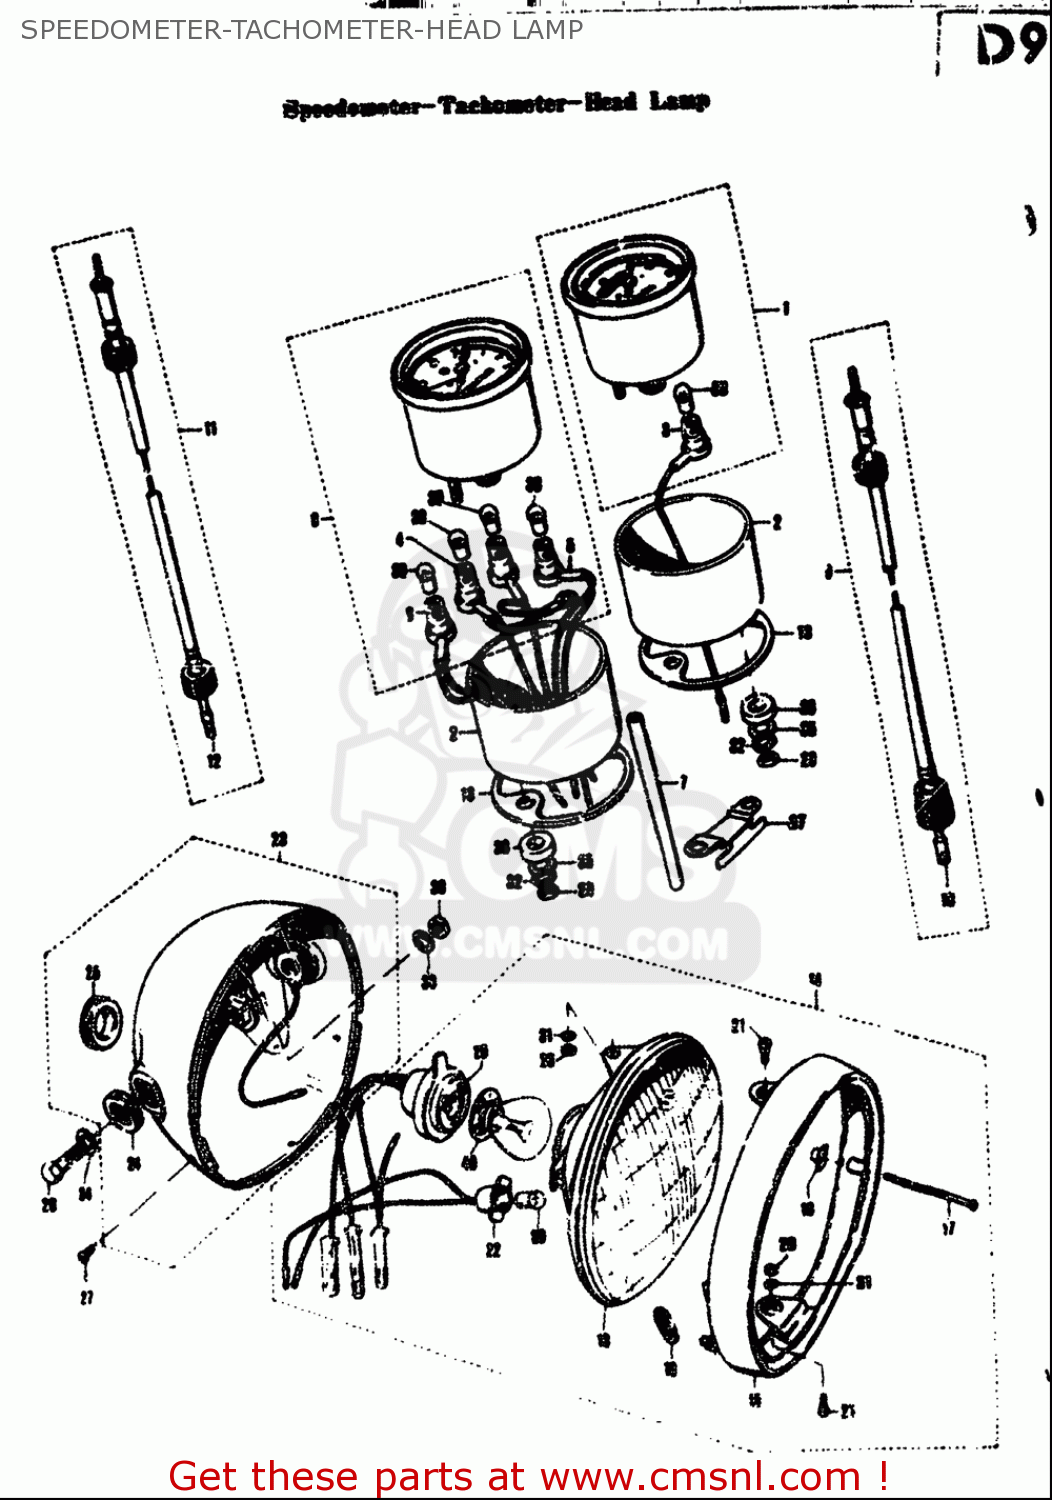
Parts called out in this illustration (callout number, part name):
11	CABLE ASSY,TACHOMETER
18	NUT
19	SPRING,HEADLAMP ADJUST
21	H/LAMP LENS UNIT FITING SCRE
22	SOCKET
26	BOLT
28	NUT
29	NUT
30	NUT
31	WASHER,LOCK
32	WASHER,LOCK
33	WASHER,LOCK
34	WASHER
35	WASHER (5.5X18X1.6)
36	CUSHION
38	BULB(12V3.4W,STANLEY,A72A)
39	BULB(12V1.7W,A71A)
